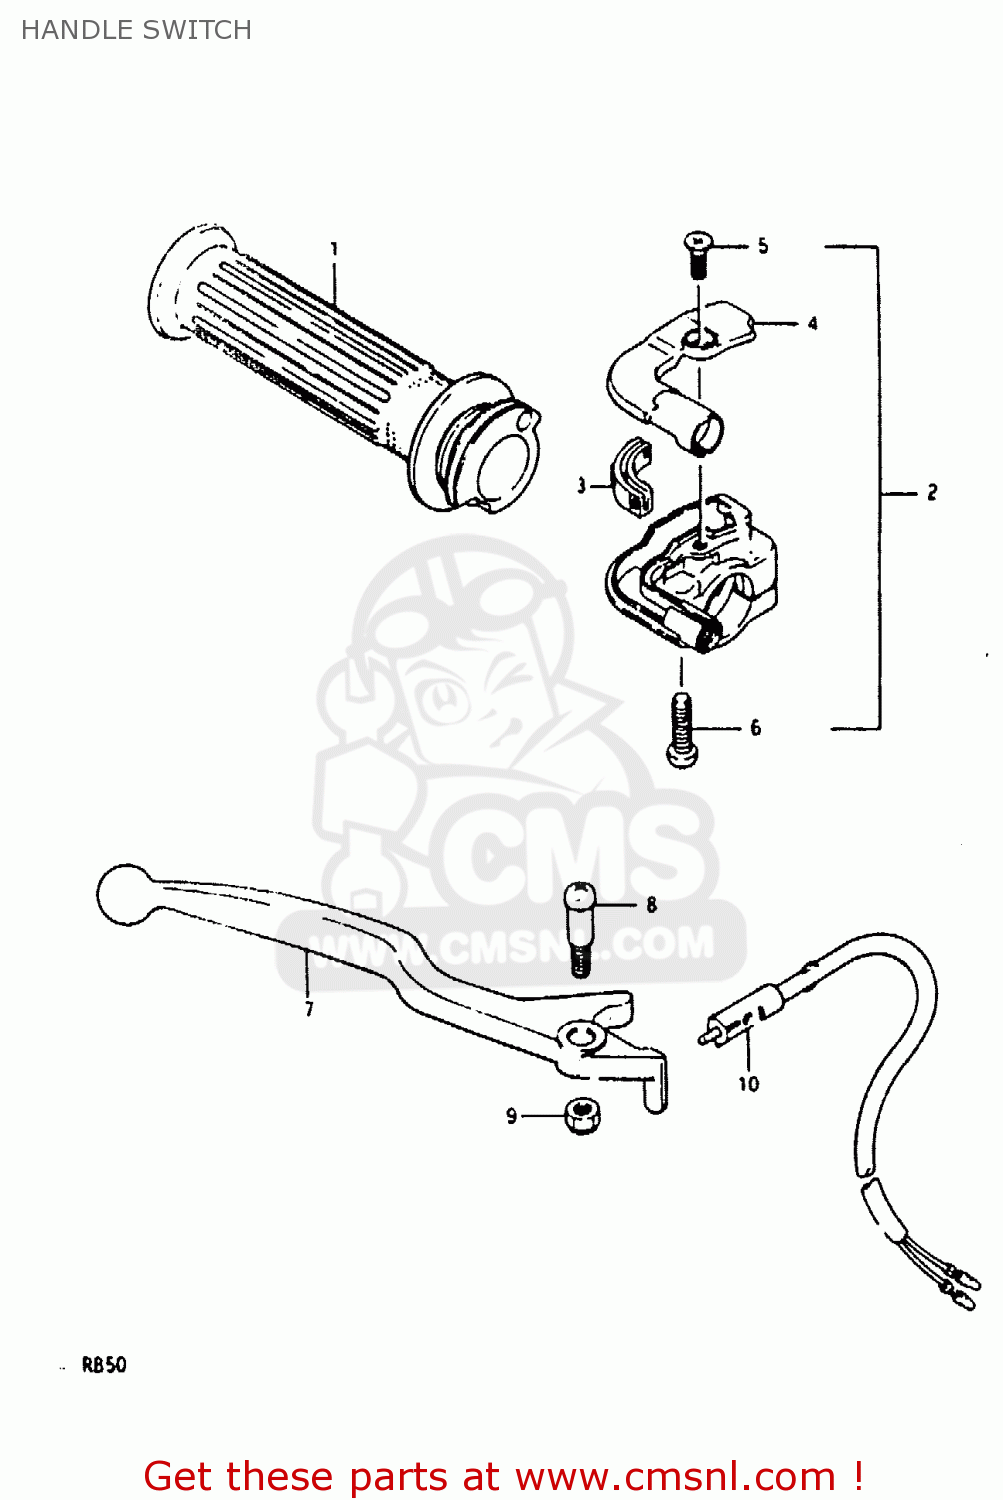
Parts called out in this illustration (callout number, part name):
1	GRIP,THROTTLE
2	CASE ASSEMBLY,THROTTLE
3	GUIDE PIECE,THROTTLE
4	COVER,THROTTLE CASE
5	SCREW 4X10
6	SCREW
7	LEVER,BRAKE
8	SCREW
9	NUT
10	SWITCH ASSY,STOP
